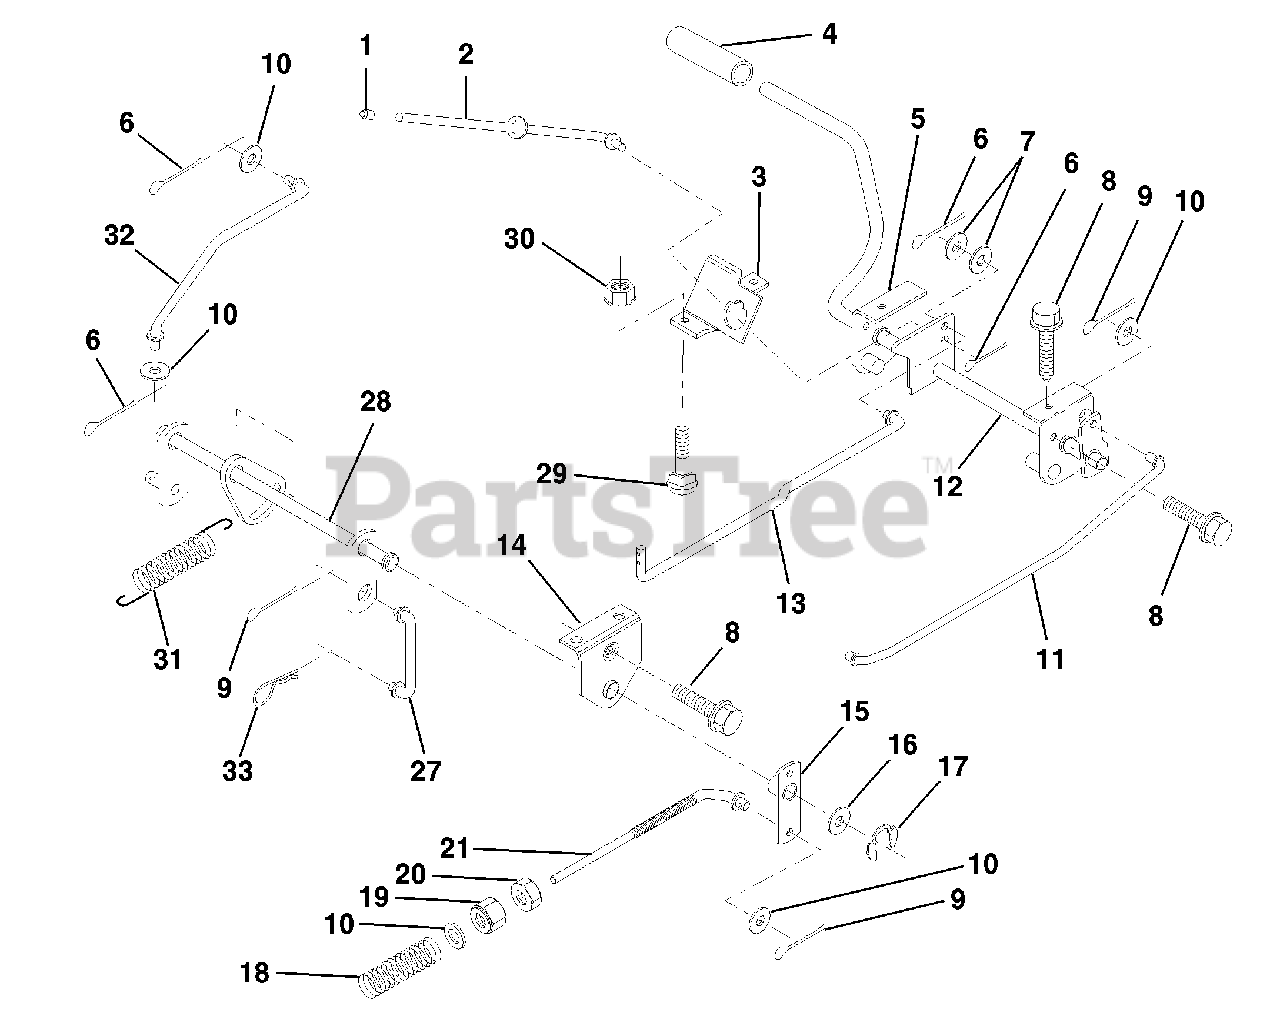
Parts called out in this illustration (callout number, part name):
1	Cap, Plunger
2	Rod, Parking Brake
3	Bracket, Parking Brake
4	Cover, Pedal
5	Bracket, Clutch/Brake Pedal, L.H.
6	Pin, Cotter 3/32 x 3/4
7	Washer 13/32 x 5/8 x 16 Gauge
8	Screw, Hex Head, Thd., Roll. 5/16-18 x 1/2
9	Pin, Cotter 1/8 x 3/4
10	Washer 13/32 x 13/16 x 16 Gauge
11	Rod, Brake, Front
12	Assembly, Clutch/Brake Pedal
13	Rod, Clutch
14	Bracket, Lift Shaft
15	Assembly, Brake, Pivot, Arm
16	Washer 25/32 x 1-1/8 x 16 Gauge
17	Ring, Klip
18	Spring, Brake Rod
19	Nut, Crownlock 3/8-16 UNC
20	Nut, Hex, Jam 3/8-16 UNC
21	Rod, Brake, Rear
27	Link, Lift, Rear
28	Assembly, Rear Mower Lift
29	Bolt, Carriage 5/16-18 UNC x 3/4
30	Nut, Hex, Keps 5/16-16 UNC
31	Spring, Counterbalance
32	Link, Lift Lever
33	Retainer Spring
